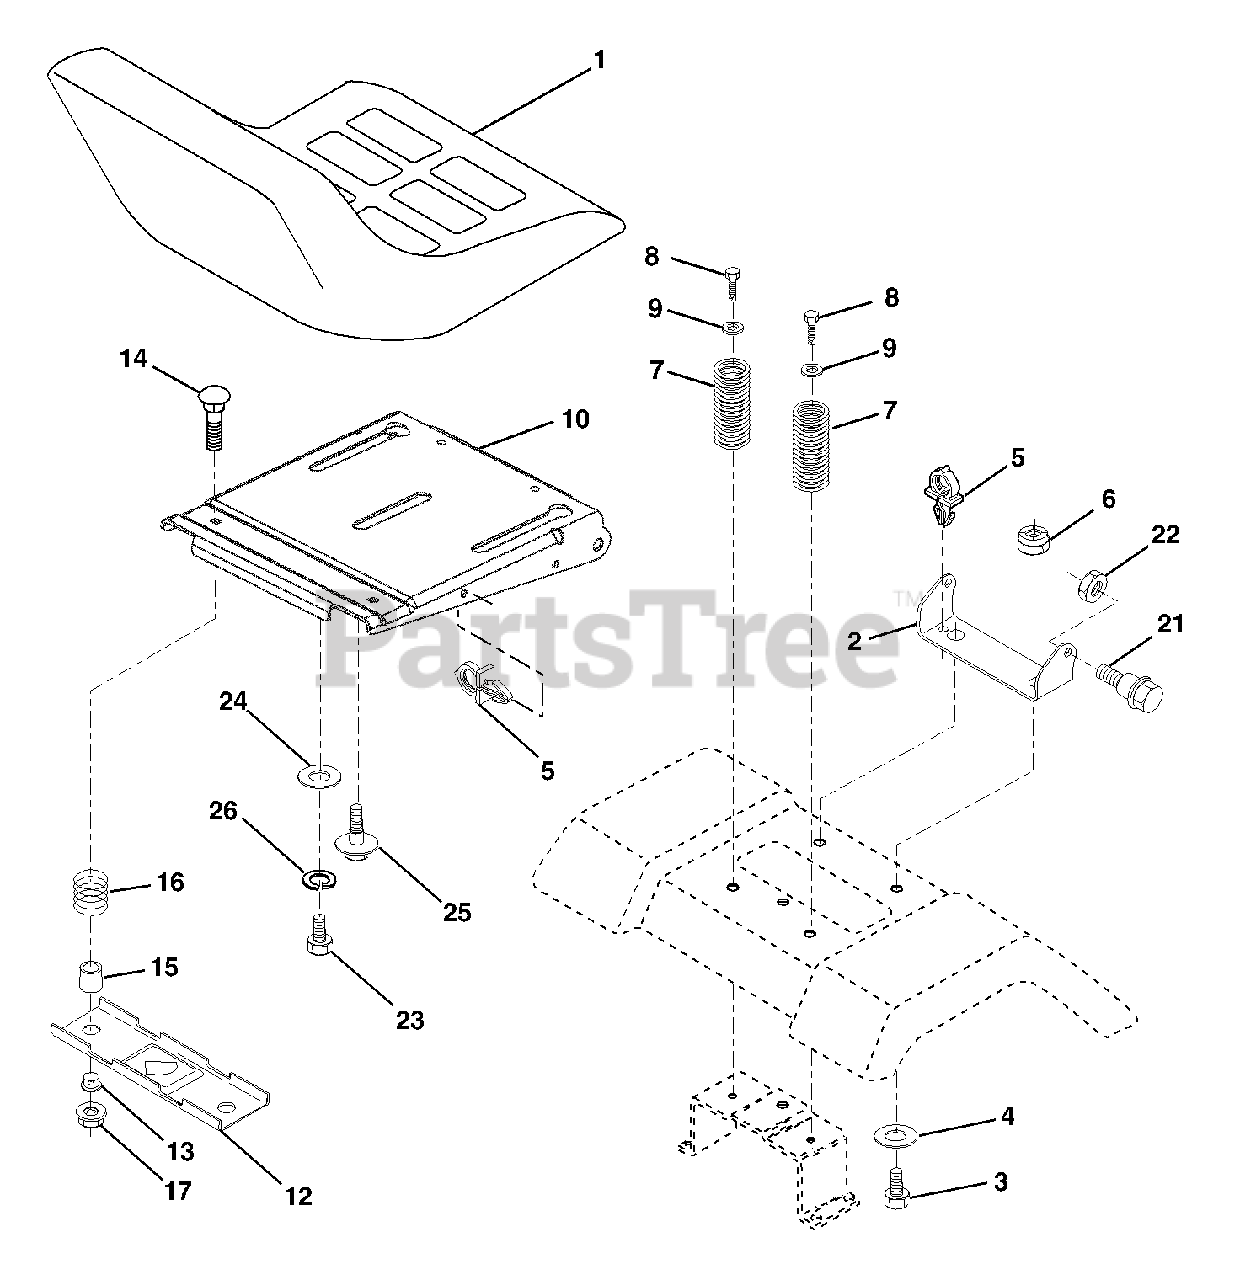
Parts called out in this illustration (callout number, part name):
2	Bracket Pivot Fender
3	Bolt
4	Washer 13/32 x 1 x 10 Ga
5	Clip Push-In Hinged
6	Nut
7	Spring Seat Cprsn 2 250 Blk Zi
8	Screw 3/8-16 x 1.5
9	Washer 13/32 x 1 x 14 Ga
10	Pan Seat
12	Bracket Pnt Mounting Switch
13	Bushing Snap Blk Nyl 50 Id
14	Bolt Rdhd Sht Nk 1/4-20 x 1-1/2
15	Spacer Split 28 x 96 Yel Zinc
16	Spring Cprsn 1 27 Blk Pnt
17	Nut Lock 1/4 Lge Flg Gr 5 Zinc
21	Bolt Shoulder 5/16-18 Unc Blkz-2A
22	Nut
23	Bolt Hex Black
24	Washer 17/32 x 1-3/16 x 12 Ga
25	Bolt Shoulder 5/16-18 x 62
26	Lockwasher
